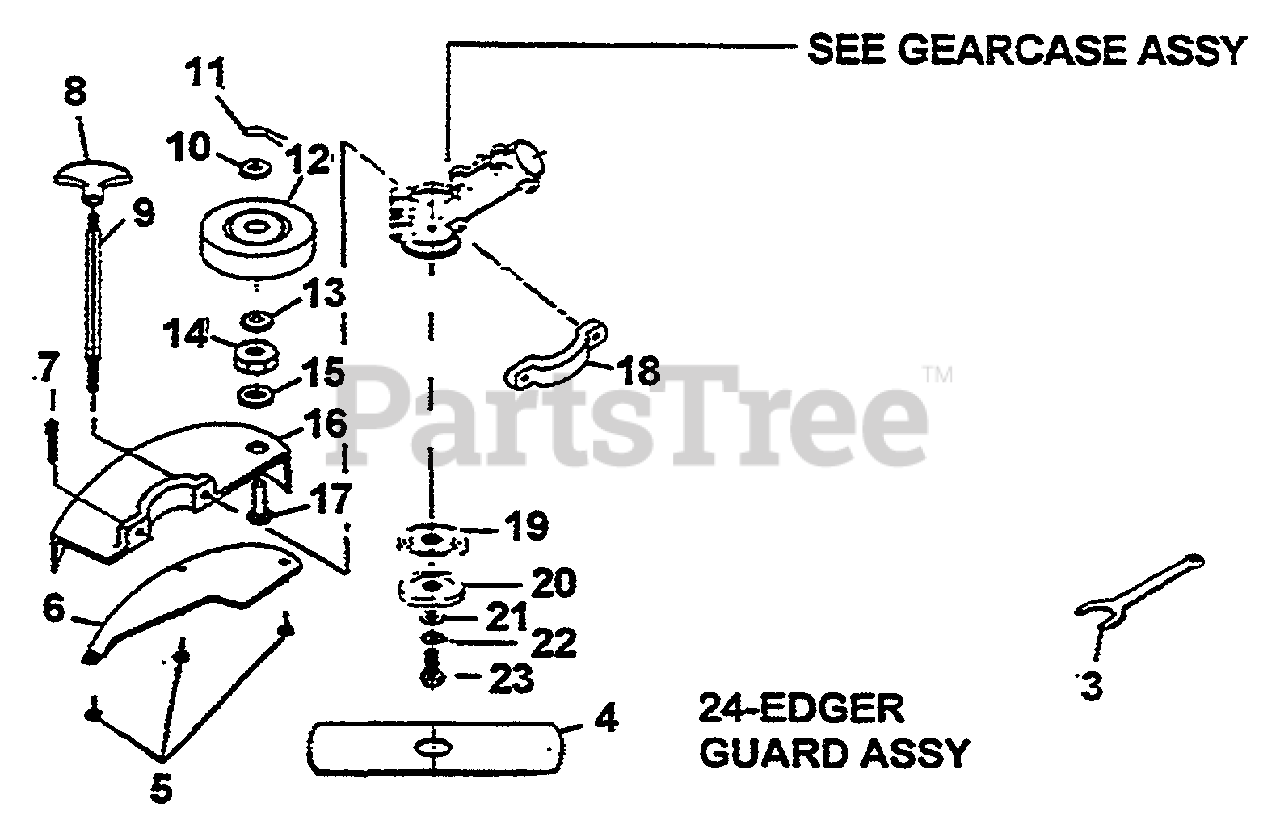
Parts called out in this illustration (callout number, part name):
3	SPANNER WRENCH
4	EDGER BLADE
5	SCREW
6	EDGER SHIELD
8	KNOB
9	SHAFT & KNOB KIT
11	COTTER PIN
14	NUT
16	EDGER GUARD
17	EDGER AXLE
20	HOLDER B
22	WASHER
23	BOLT
24	EDGER GUARD ASSY
